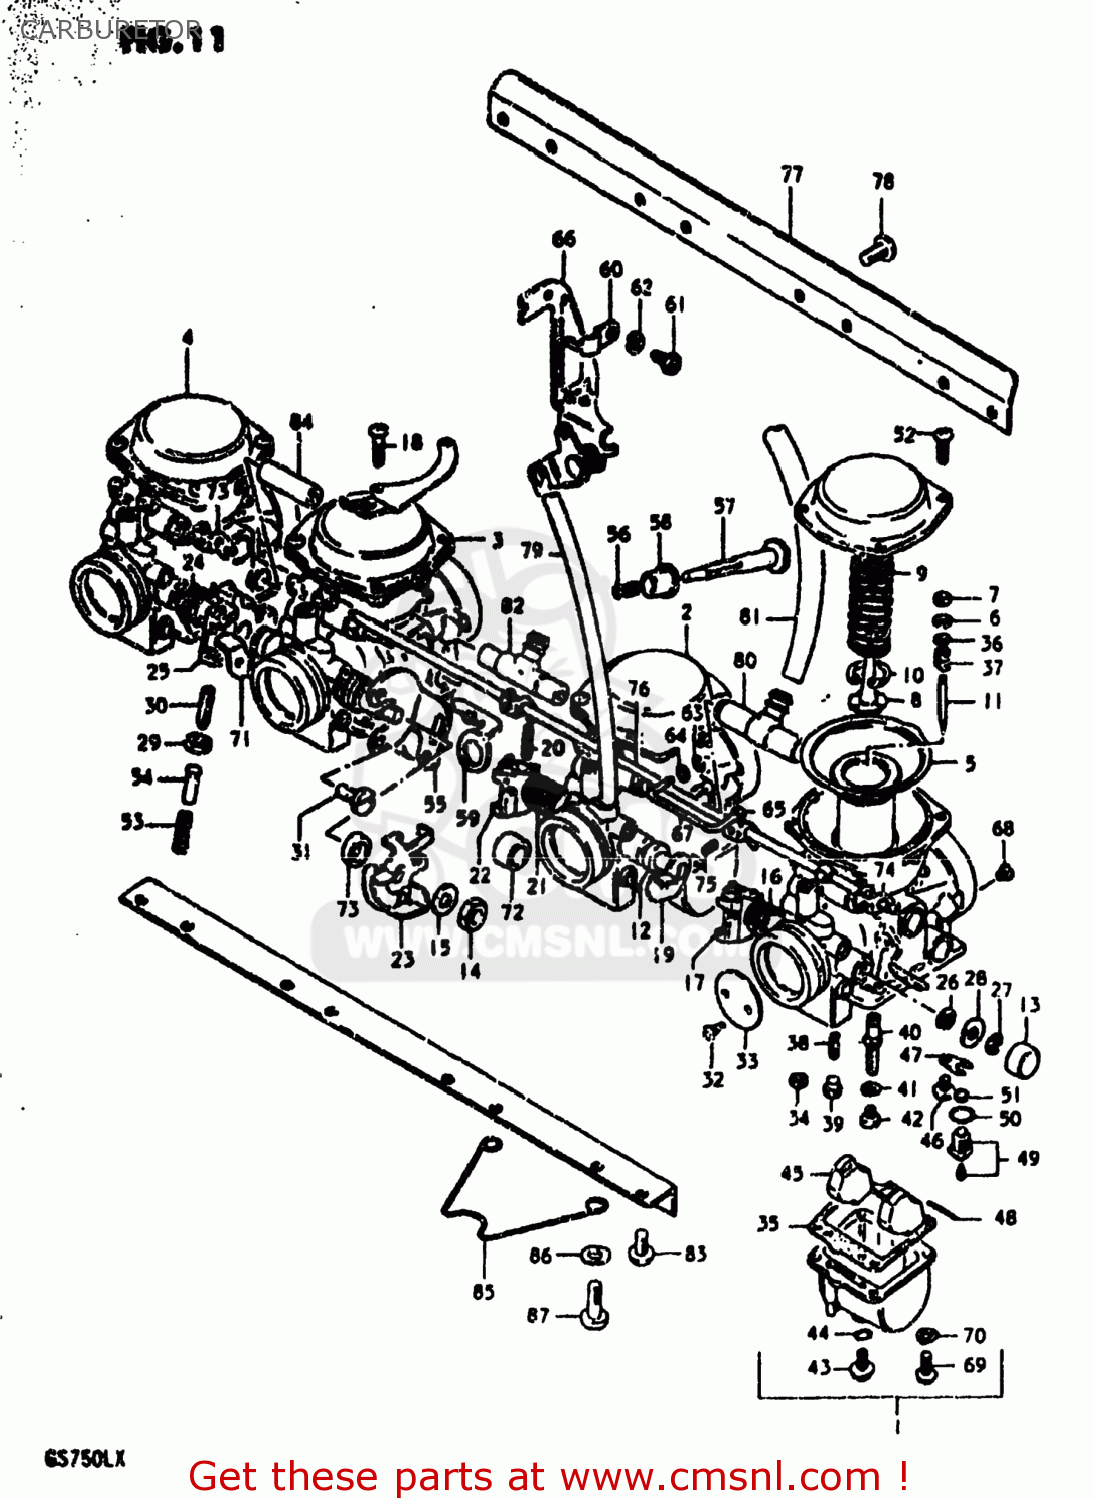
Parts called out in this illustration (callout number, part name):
1	CARBURETOR ASSEMBLY
2	CARBURETOR ASSEMBLY
3	CARBURETOR ASSEMBLY
4	CARBURETOR ASSEMBLY
5	DIAPHRAGM
6	CLIP,NEEDLE
7	RING
8	HOLDER,GUIDE
9	SPRING
10	E RING
11	NEEDLE JET
12	GASKET
13	CAP
14	NUT
15	WASHER
16	SPRING,THROTTLE SHAFT
17	SHAFT,THROTTLE
18	SCREW
19	SHAFT,THROTTLE
20	PIN,THROTTLE SHAFT
21	SPRING,THROTTLE SHAFT
22	LEVER,THROTTLE SHAFT
23	LEVER ASSEMBLY,THROTTLE
24	SPRING,THROTTLE SHAFT
25	SHAFT,THROTTLE
26	SEAL
27	E RING
28	GASKET,THROTTLE SHAFT (NAS)
29	NUT
30	SCREW
31	SCREW
32	SCREW
33	VALVE,THROTTLE
34	GASKET (NAS)
35	GASKET,FLOAT CHAMBER (NAS)
36	WASHER
37	SPRING
38	JET,PILOT(42.5)
39	PLUG,NEEDLE JET
40	JET,NEEDLE
41	WASHER,NEEDLE NOZZLE
42	JET,MAIN(112.5)
43	PLUG,DRAIN
44	GASKET (NAS)
45	FLOAT
46	SCREW
47	PLATE
48	PIN,FLOAT
49	VALVE ASSEMBLY,NEEDLE
50	O-RING,NEEDLE VALVE
51	FILTER
52	SCREW
53	SPRING,THROTTLE SCREW
54	PIN,THROTTLE LEVER
55	BRACKET,THROTTLE ADJUST
56	SPRING
57	SCREW
58	BUSH
59	BRACKET,THROTTLE ADJUST
60	BRACKET,STARTER
61	BOLT
62	LOCK WASHER
63	CAP,LEVER
64	SEAT,SPRING
65	LEVER ASSY
66	BRACKET
67	ROD,STARTER LEVER
68	JET,AIR
69	SCREW
70	LOCK WASHER
71	SHAFT,THROTTLE
72	RING
73	RING
74	LEVER
75	SCREW
76	SHAFT,STARTER
77	BRACKET
78	SCREW
79	HOSE
80	NIPPLE,CARBURETOR
81	HOSE
82	NIPPLE
83	SCREW 6X12
84	NIPPLE
85	CLAMP
86	WASHER
87	SCREW
